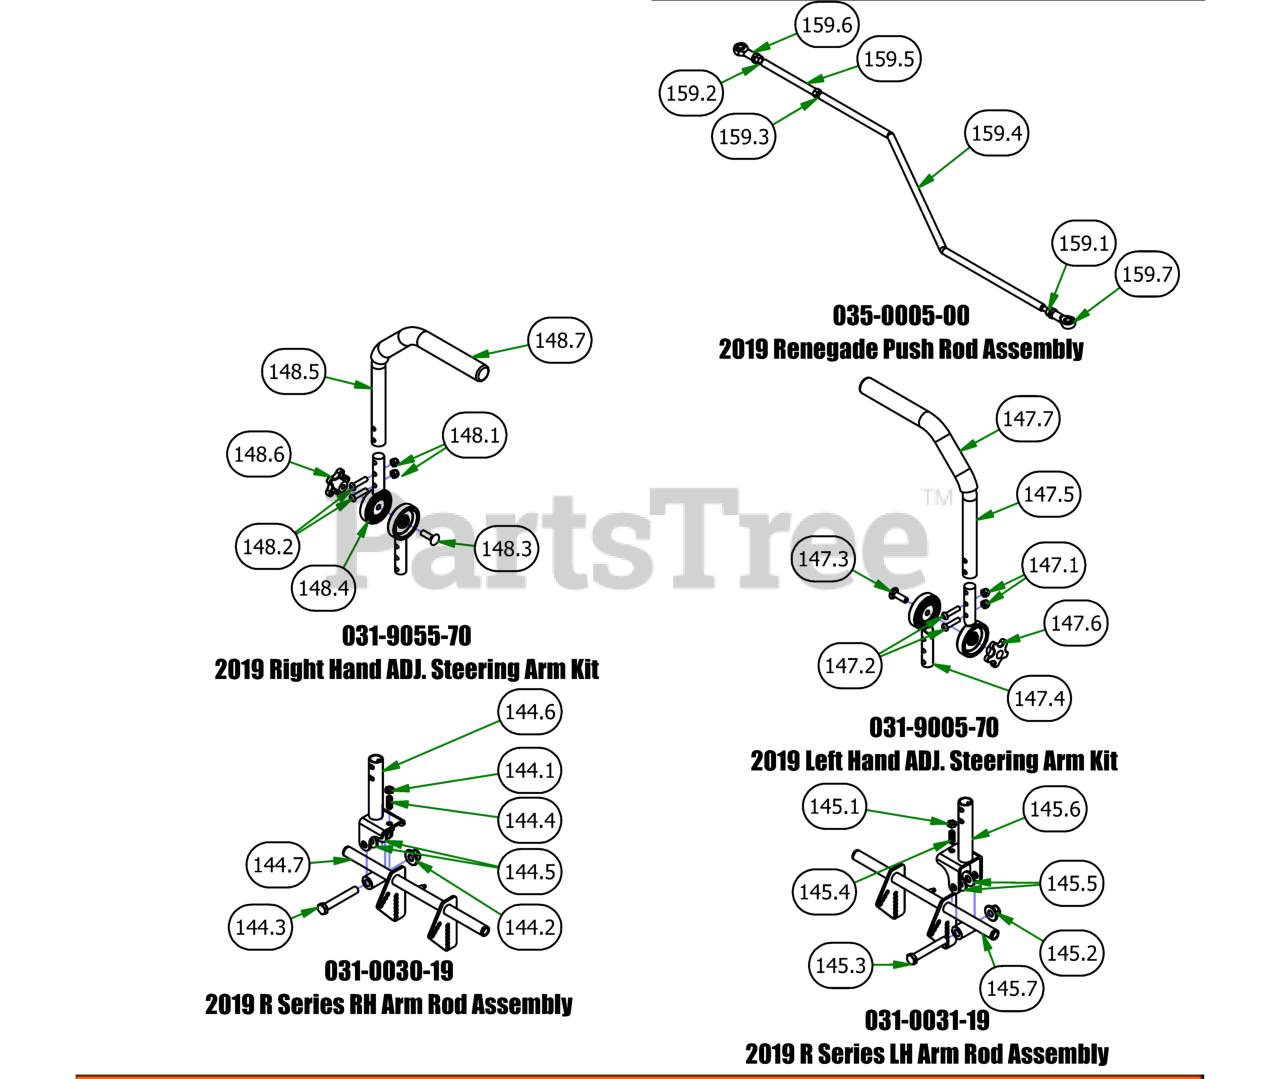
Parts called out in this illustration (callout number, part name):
144.1	3/8-16 Half Jam Nut
144.2	1/2-13 NYLON INSERT FLANGE LOCKNUT ZINC
144.3	1/2-13 x 3.25 GR 5 Hex Bolt Zinc
144.4	3/8-16 x 1 Set Socket Set Screw Cup Point
144.5	.505 Nylon Spacer
144.6	Drive Arm Pivot
144.7	2019 Drive Arm Actuator right
145.1	3/8-16 Half Jam Nut
145.2	1/2-13 NYLON INSERT FLANGE LOCKNUT ZINC
145.3	1/2-13 x 3.25 GR 5 Hex Bolt Zinc
145.4	3/8-16 x 1 Set Socket Set Screw Cup Point
145.5	.505 Nylon Spacer
145.6	Drive Arm Pivot
145.7	2019 Drive Arm Actuator left
147.1	5/16-18 Nylock Insert Locknut
147.2	5/16-18 UNC X 1-3/8" BHCS, TORX DRIVE, GR 5
147.3	3/8" x 1 1/4" Carriage Bolt
147.4	2019 Steering Arm Adjuster Casting
147.5	2019 Steering Arm Grip
147.6	Black Knob for Adjustable Steering Arm
147.7	Black Steering Arm Grip
148.1	5/16-18 Nylock Insert Locknut
148.2	5/16-18 UNC X 1-3/8" BHCS, TORX DRIVE, GR 5
148.3	3/8" x 1 1/4" Carriage Bolt
148.4	2019 Steering Arm Adjuster Casting
148.5	2019 Steering Arm Grip
148.6	Black Knob for Adjustable Steering Arm
148.7	Black Steering Arm Grip
159.1	5/16" RH Fine Threaded Jam Nut
159.2	5/16" LH Fine Threaded Jam Nut
159.3	3/8" Fine Threaded Jam Nut
159.4	2019 Renegade Push Rod
159.5	2019 Renegade Push Rod Adjuster
159.6	Spherical Rod End - Outlaw
159.7	Spherical Rod End - Outlaw
